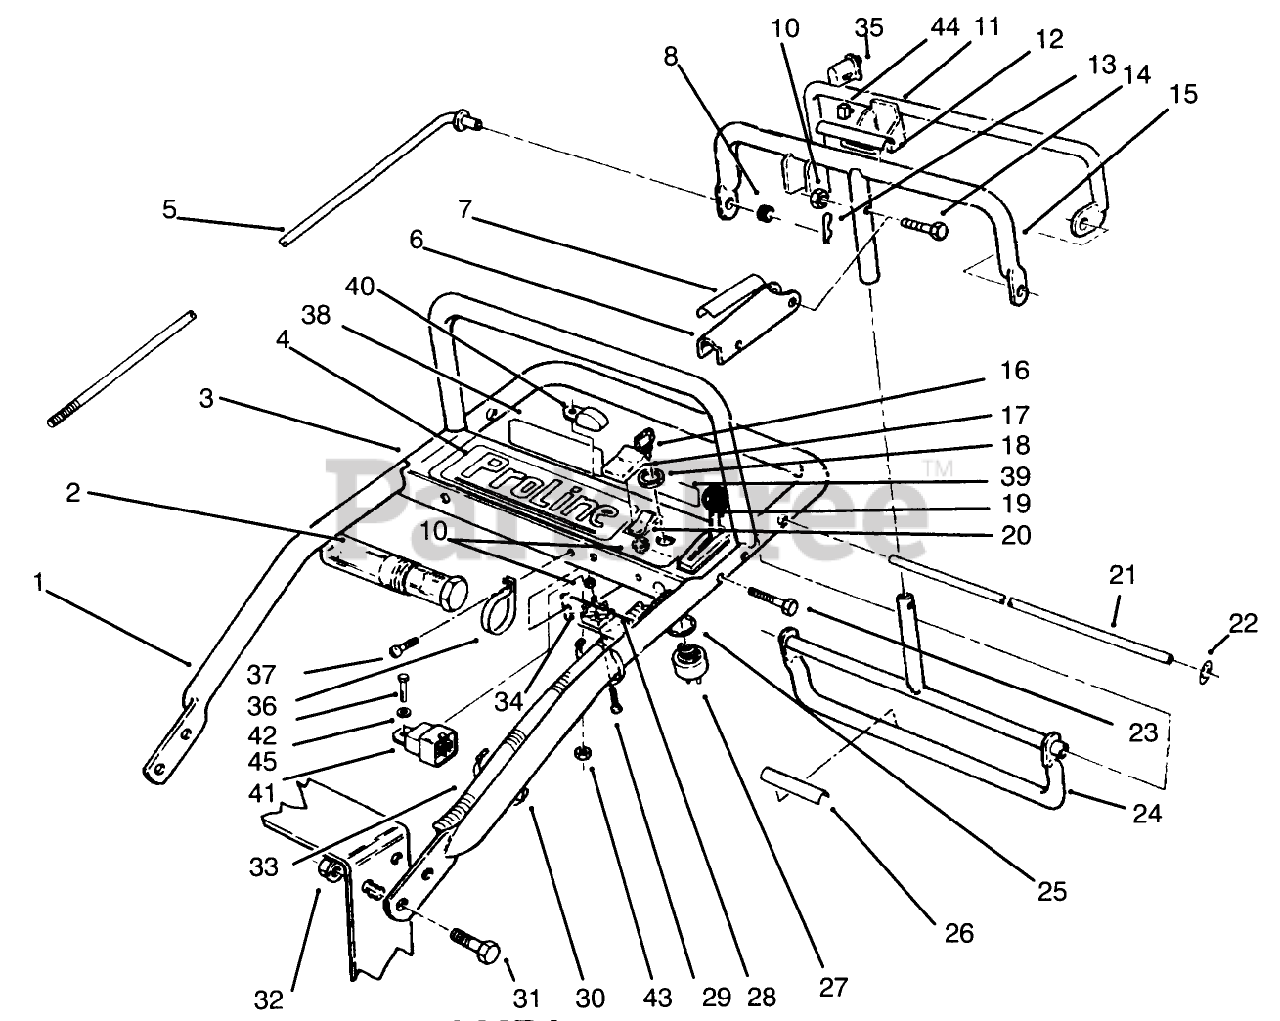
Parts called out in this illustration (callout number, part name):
1	Handle-Upper
2	TUBE-MANUAL
3	Panel-Control
4	DECAL-CONTROL PANEL
5	ROD-CONTROL
6	Lever-Parking Brake
7	DECAL-LEVER, PARKING
8	GROMMET-RUBBER
10	NUT-LOCK, NI
11	Bail
12	DECAL
13	PIN-COTTER
14	SCREW-SHH
15	Bar
16	KEY-IGNITION
17	BOOT-SWITCH
18	NUT-HH
19	CONTROL-THROTTLE
20	SWITCH
21	PIVOT ROD
22	NUT-PUSH-ON, CIRCULAR
23	SCREW-SHH
24	Control Pivot
25	WASHER-TOOTH, INTERNAL
26	DECAL
27	Switch-Off/On (Incl. Ref. #16, 18, & 25)
28	Panel-Bottom
29	SCREW-HWH
30	TIE-CABLE
31	SCREW-HHF
32	NUT-HF
33	Wire Harness (Ref.)
34	RECTIFIER-BRIDGE
35	SWITCH-BAIL
36	CLAMP-R
37	SCREW-SHWH
38	DECAL-INSTRUCTION
39	DECAL-INSTRUCTION, SAFETY
40	Module
41	RELAY
42	SCREW-HH
43	NUT-LOCK, NI
44	CONNECTOR-BODY
45	WASHER-LOCK/EXT
